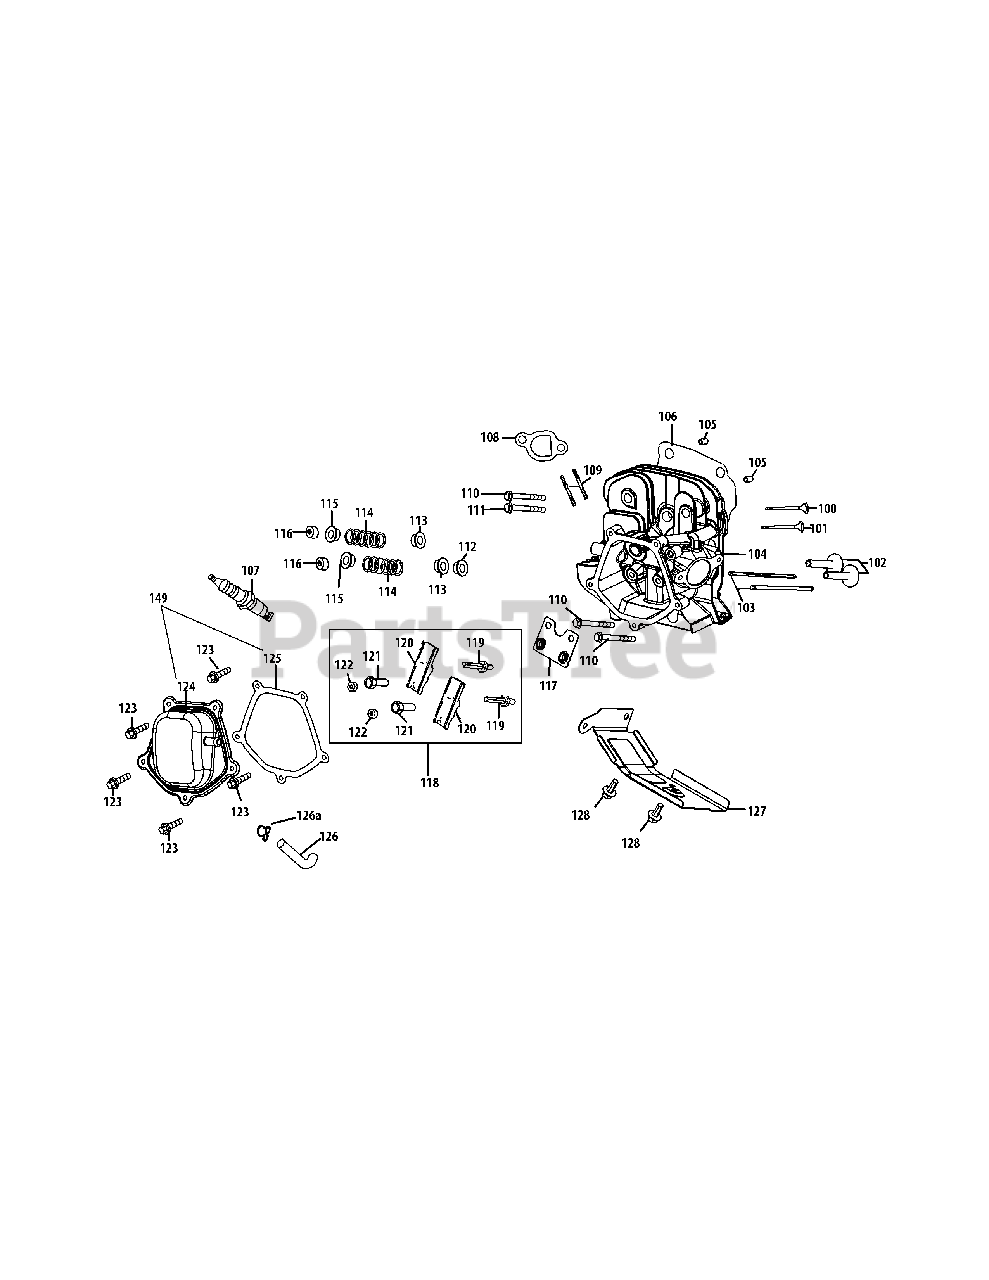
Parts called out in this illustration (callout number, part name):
100	Valve Kit
101	Valve Kit
102	Tappet
103	Push Rod
104	Cylinder Head Kit
105	Dowel Pin 12×20
106	Gasket Cylinder Head
107	Spark Plug
108	Exhaust Pipe Gasket
109	Stud M8×48.5
109	Muffler Stud Assembly
110	Bolt M10×1.25×87
111	Bolt M10×1.25×65
112	Intake Valve Seal
113	Valve Spring Retainer
114	Valve Spring
115	Retainer Exhaust Valve Spring
116	Adjuster Exhaust Valve
117	Push Rod Guide
118	Rocker Arm Assembly
119	Bolt Pivot
120	Rocker Arm
121	Adjusting Nut, Valve
122	Nut Pivot Locking
123	Valve Cover Bolt
124	Valve Cover
125	Valve Cover Gasket
126	Breather Hose
127	Air Shield
128	Bolt M6×12
149	Valve Cover Kit
